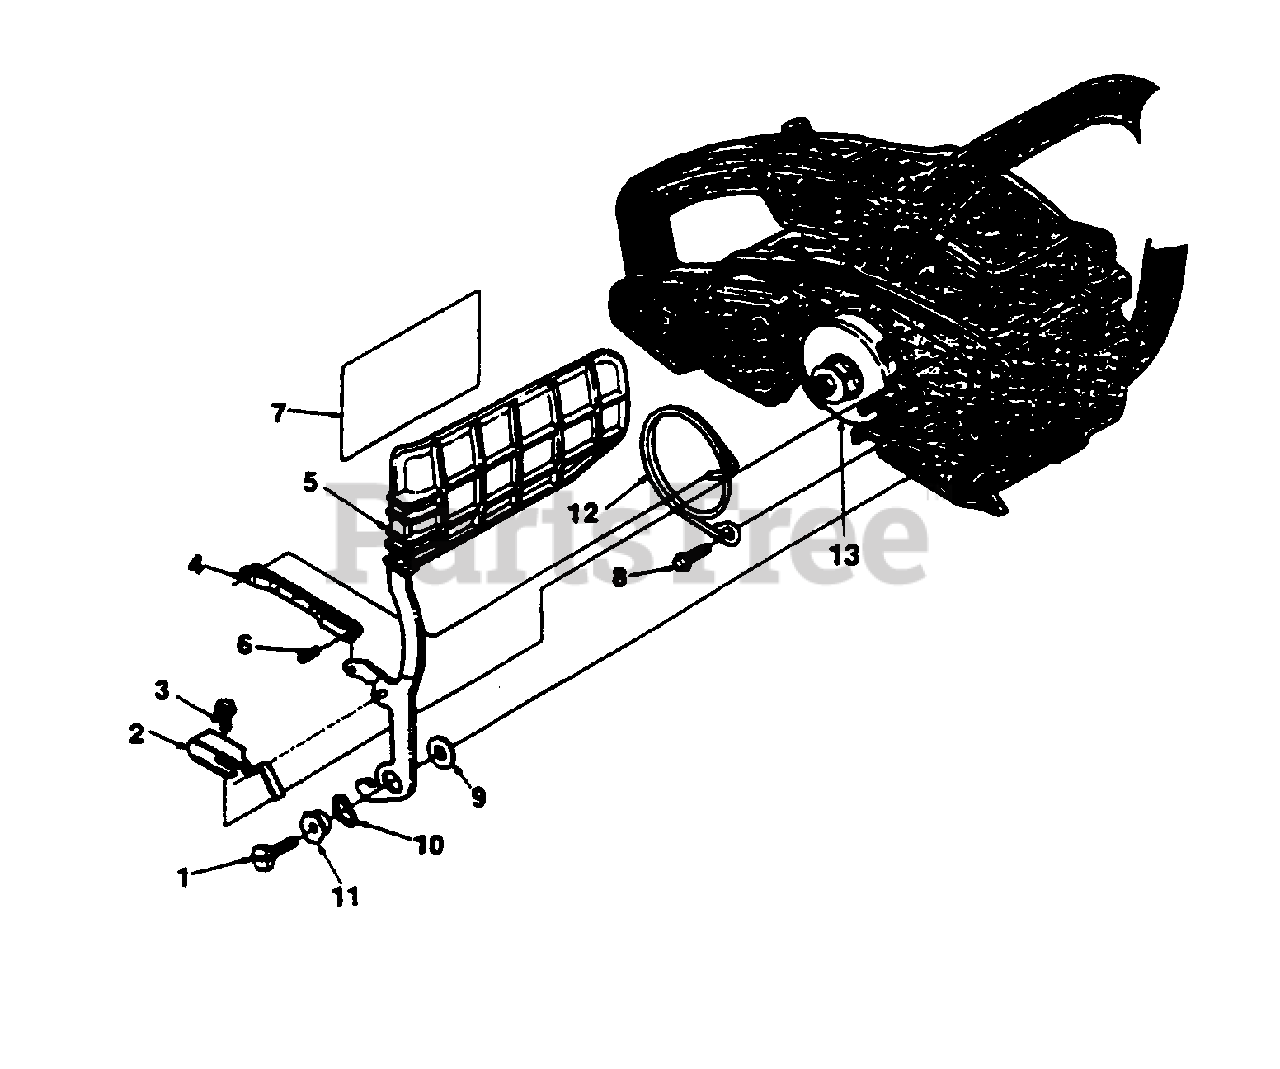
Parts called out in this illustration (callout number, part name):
1	SCREW- Hex cap 1/4-20 x 5/8
2	CLIP- Retaining
3	SCREW- Hex Sems 10-24 x 3/8
4	LINK- Pivot
5	HAND GUARD
6	PIN- Roll
7	DECAL
8	SCREW- Hex Sems 10-24 x 5/8
9	WASHER- Thrust
10	WASHER- Curved
11	CAM- Brake lever
12	BAND- Brake
13	SPROCKET & DRUM .325P-8T
